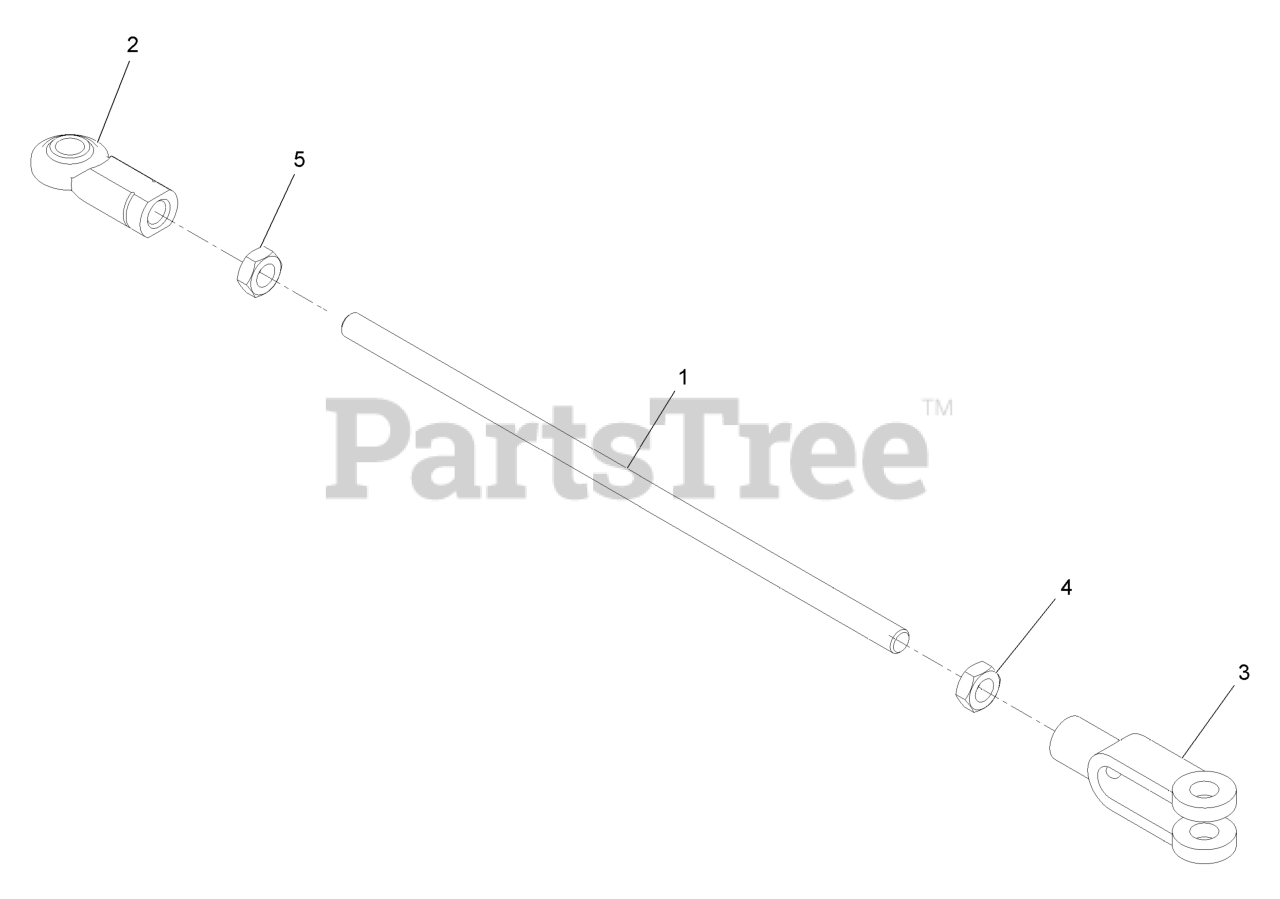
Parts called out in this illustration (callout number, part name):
1	ROD-BRAKE LINKAGE
2	JOINT-BALL END, LH
3	YOKE-LINKAGE, BRAKE
4	NUT-HJ
5	NUT-HEX JAM, LH
